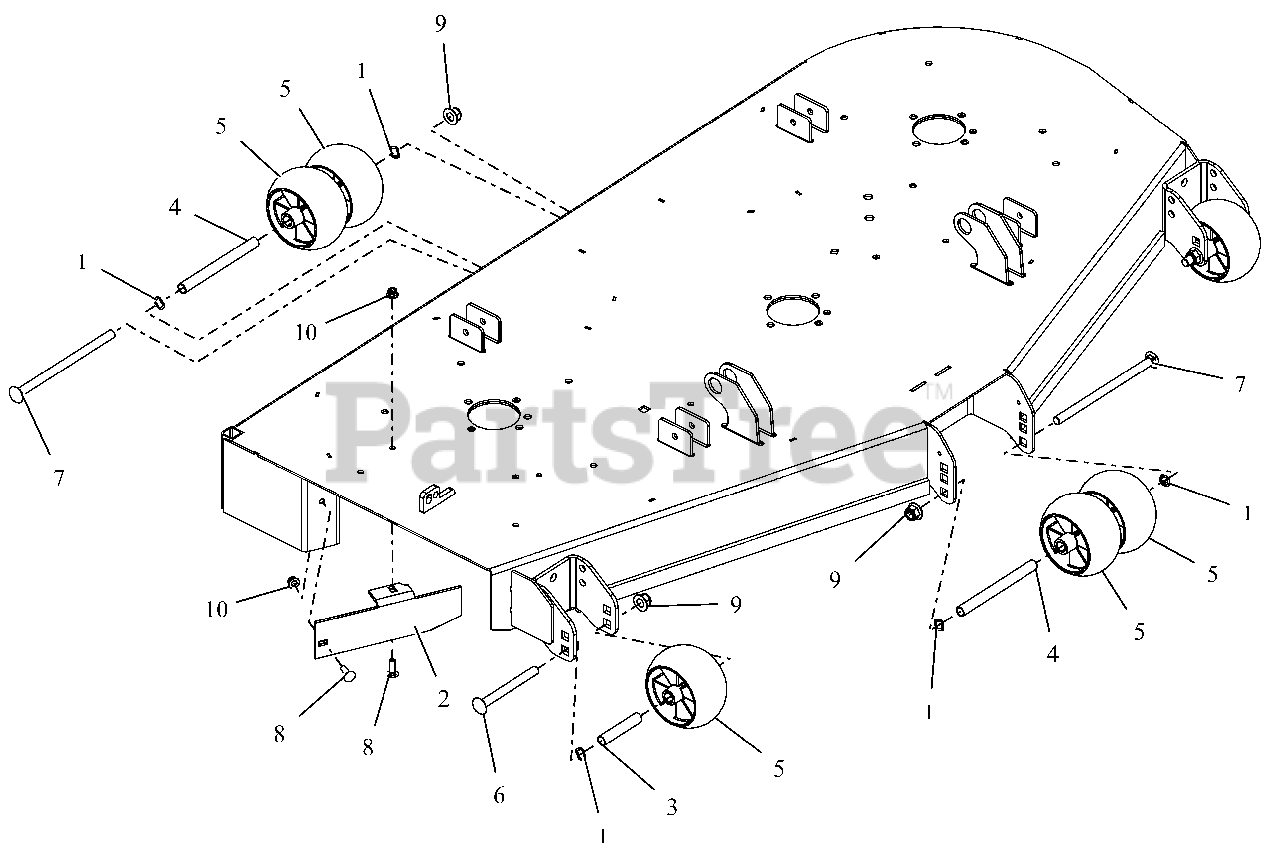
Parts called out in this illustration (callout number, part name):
1	WAVE WASHER .531X.781X.125FH
2	60" DISCHARGE BAFFLE - RED
3	SPACER, .510X.625X3.35
4	SPACER, .510X.625X6.50
5	ANTI-SCALP WHEEL - 5X3 CTR
6	BLT-RDHDSQNK .50-13X5.00 GR5YZ
7	@BLT-RDHDSQNK .50-13X8.50 G5YZ
8	@BLT-RDHDSQNK .31-18X1.00 G5YZ
9	@NUT-LK-NYL-FLG .50-13 YWZC
10	@NUT-LK-NYL-FLG .31-18 YWZC
